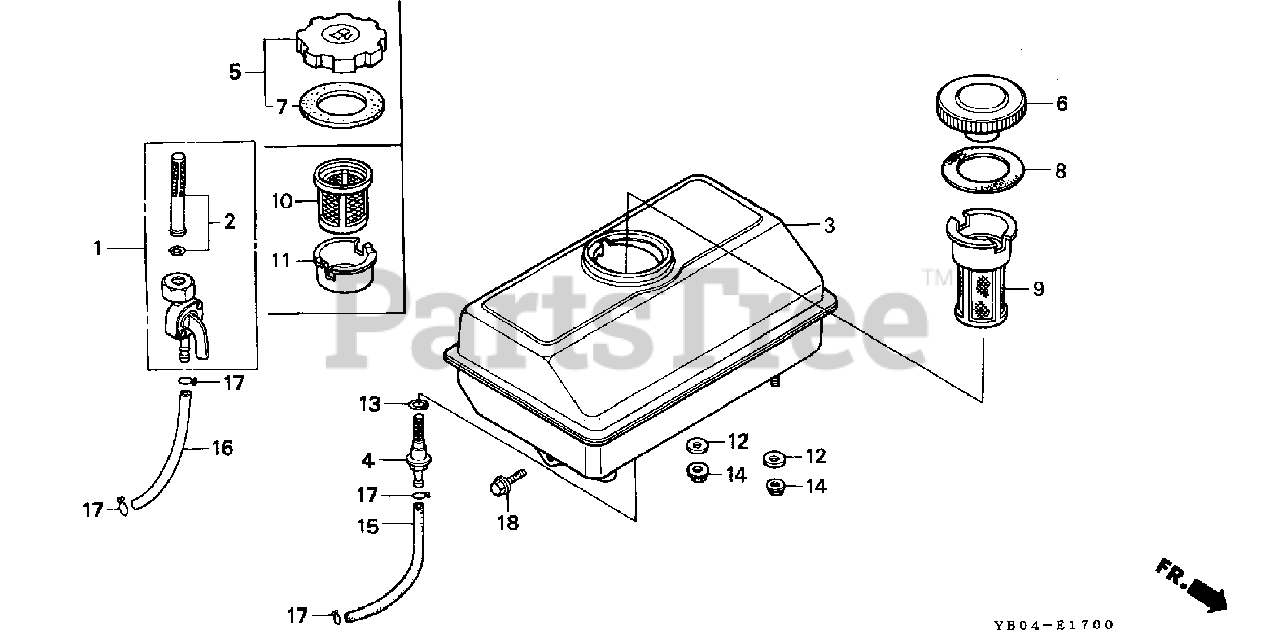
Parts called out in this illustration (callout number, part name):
3	TANK ASSY., FUEL *NH31* (MCKINLEY WHITE)
3	TANK, FUEL
3	TANK, FUEL *NH31* (MCKINLEY WHITE)
4	JOINT, FUEL TANK
6	CAP, FUEL FILLER
8	GASKET, FUEL FILLER CAP
9	FILTER, FUEL
10	FILTER, FUEL
11	HOLDER, FUEL FILTER
13	O-RING (13.5X1.5) (ARAI)
14	NUT, FLANGE (6MM)
15	BULK HOSE, FUEL (4.5X3000) (4.5X55)
17	CLIP, TUBE (B8)
18	BOLT, FLANGE (6X14)
